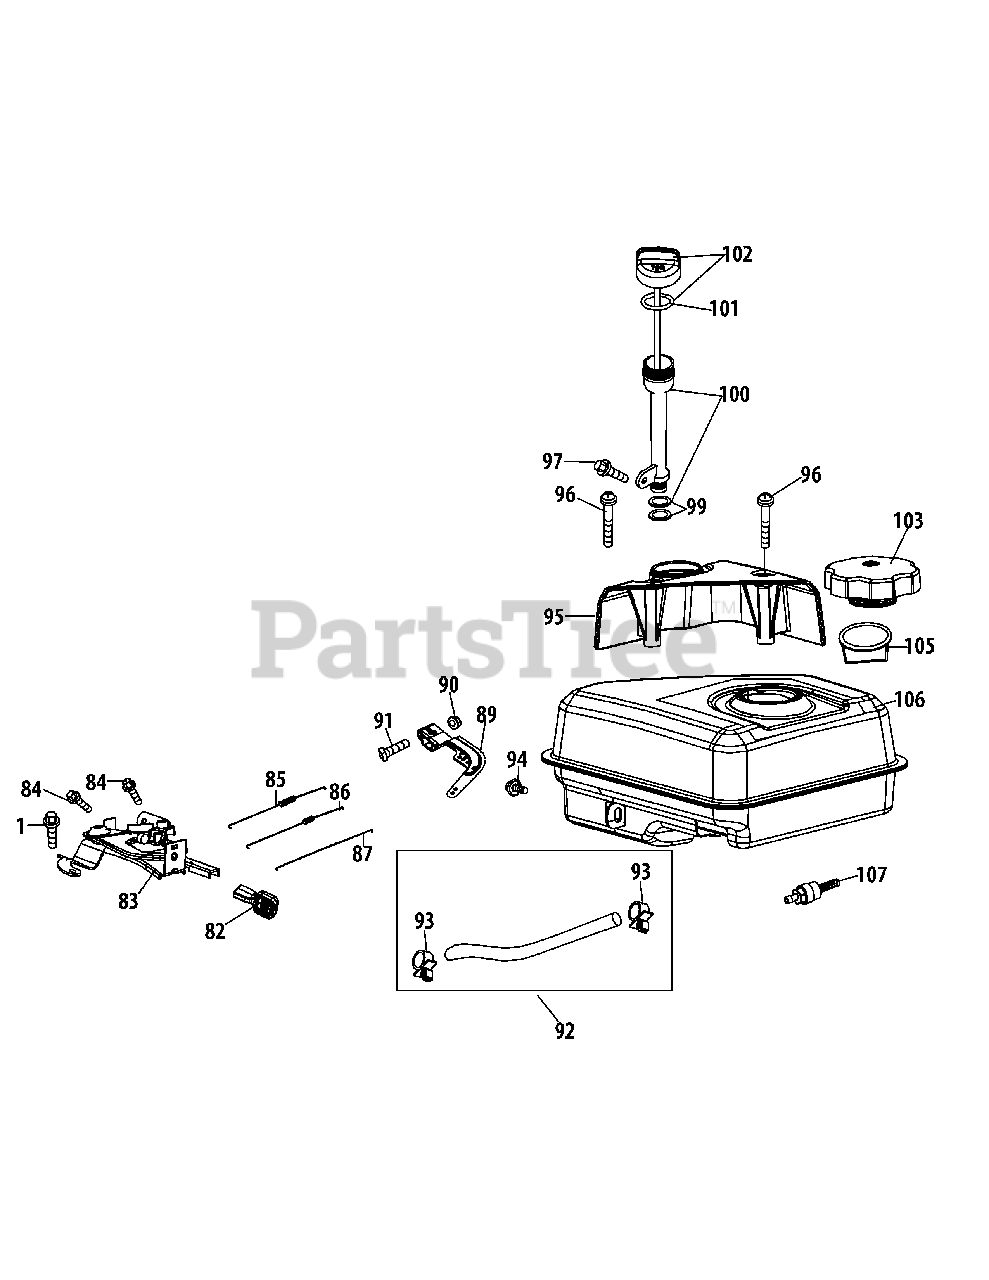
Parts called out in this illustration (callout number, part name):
1	Bolt M6×16
82	Throttle Control Knob
83	Primer Bracket
84	Bolt M6×12
85	Governor Spring
86	Throttle Linkage Spring
87	Throttle Linkage
89	Governor Arm
90	Nut M6
91	Governor Arm Bolt
92	Fuel Line Kit
93	Fuel Hose Clamp
94	Bolt M6×12
95	Dipstick Decoration Cover
97	Bolt M6×12
99	Oil Fill Tube O-Ring
100	1/ 4 Turn Oil Fill Tube
101	Dipstick O-Ring
102	Dipstick Guage
103	Fuel Cap Assembly
105	Fuel Level Indicator
107	Fuel Tank Nipple
